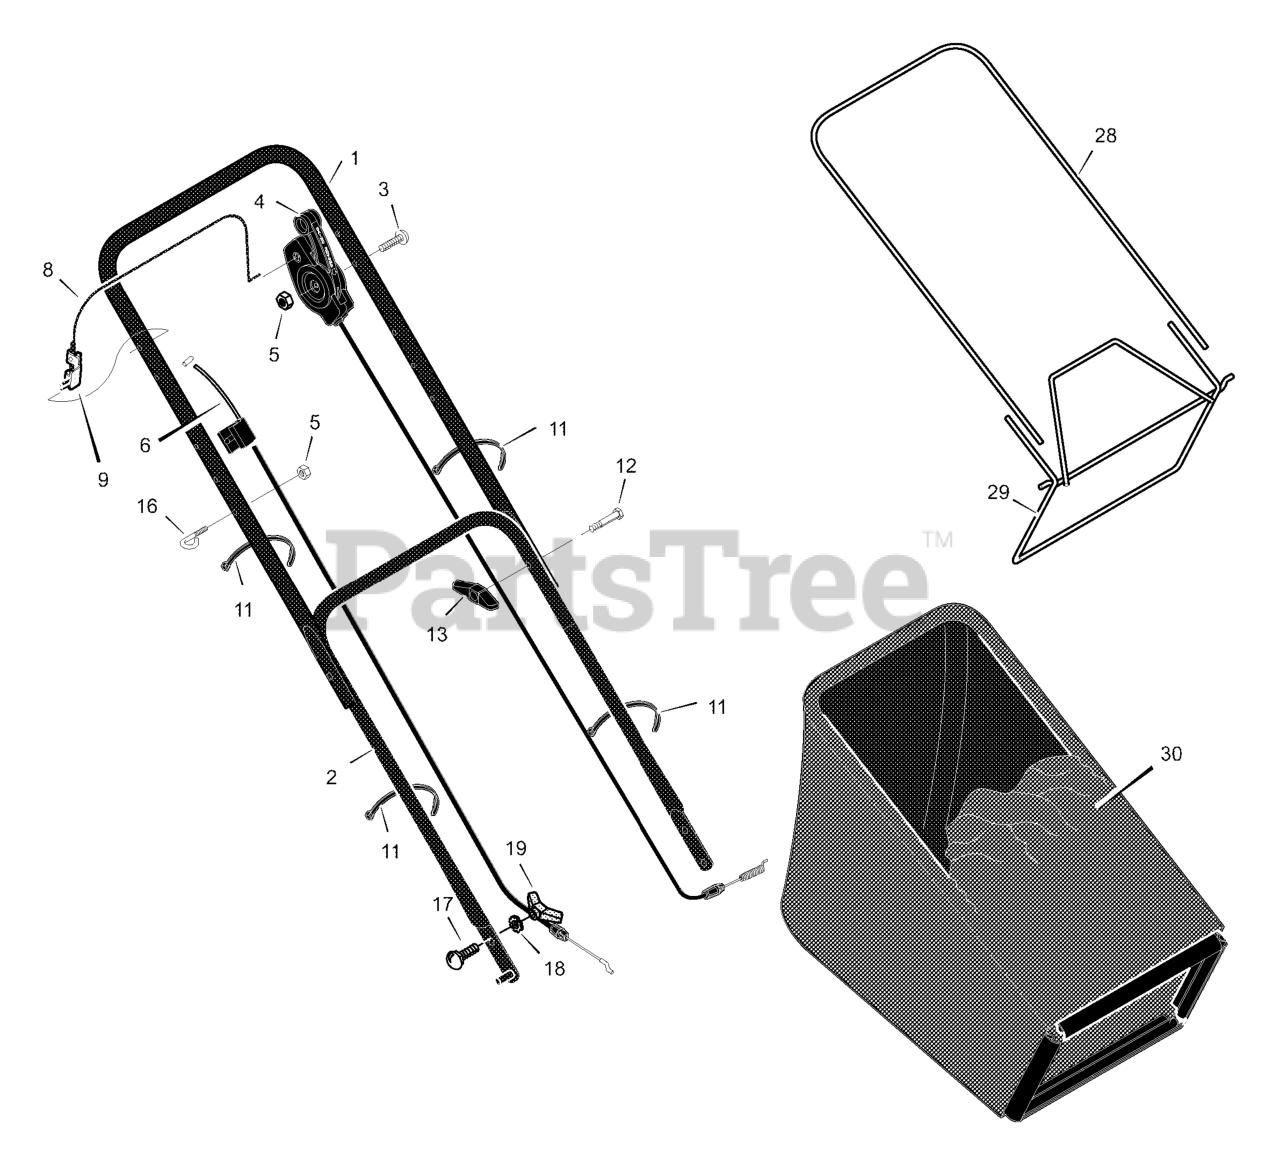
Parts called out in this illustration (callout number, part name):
1	Handle, Upper (Black)
2	Handle, Lower (Black)
4	Control, Drive
5	Locknut
6	Cable, Stop
8	Engine Stop Lever
9	Bracket, Stop Lever
11	Fastener, Cable
13	Knob
16	Guide, Rope
17	Bolt, Carriage
18	Washer
19	Knob, Plastic
28	Frame, Top
29	Frame Assembly
30	Bag, Cloth
